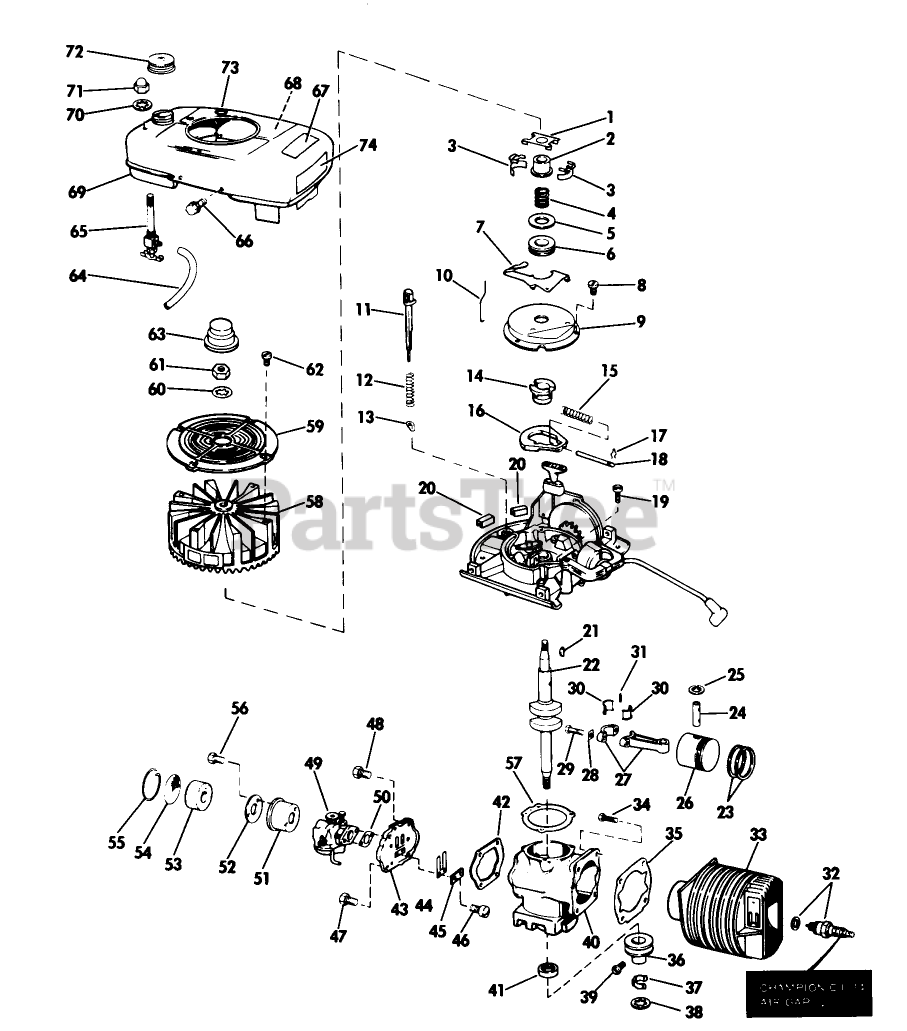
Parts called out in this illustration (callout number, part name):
2	COLLAR S
6	THRUST COLLAR S
7	LEVER-GOVERNOR S
8	SCREW S
9	DUST COVER S
12	SPRING S
14	SPARK ADV. S
15	SPARK ADV. SPRING S
16	FLYWEIGHT S
17	SPARK ADJ. SPRING
18	PIN,SPARK ADV. S
25	RING-RETAINING
28	Lockplate
30	LINER ASM
32	Spark Plug and Gasket
35	GASKET S
43	REED PLATE AY. S
45	PLATE-BACKUP, REED
47	SCREW S
48	SCREW S
50	GASKET S
52	BACK-UP PLATE
53	ELEMENT
57	GASKET S
58	FLYWHEEL S
59	Screen Cup
62	SCREW F
65	VALVE&SCREEN SM
66	SCREW S
71	PALNUT S
